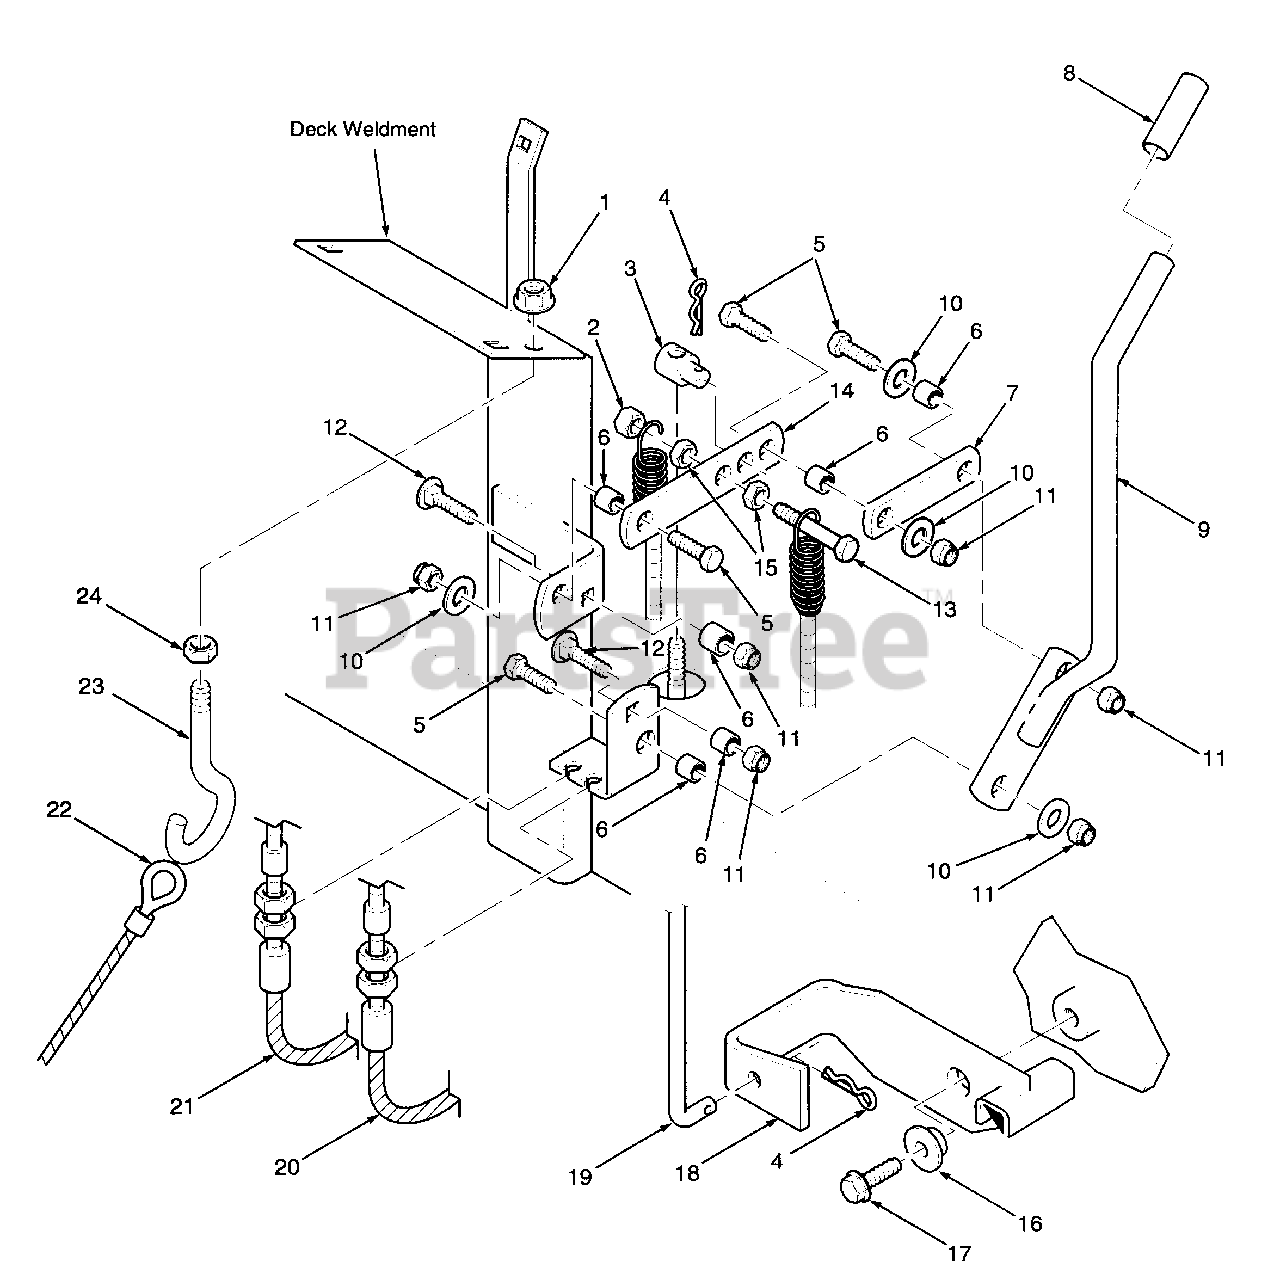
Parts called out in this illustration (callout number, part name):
1	Serr. Fl. HH Nut, 3/8-16
2	Hex Locknut, 3/8-16
3	Swivel
4	Hairpin Cotter (.094 x 1.62)
5	Hex Head Bolt, 3/8-16 x 1-1/4"
6	Sleeve, Hydro Linkage
7	Link, Cam
8	Grip, Parking Brake
9	Handle, Parking Brake
10	Flat Washer, 3/8 (.391 x .938 x .105)
11	Hex Nut, Elastic Stop 3/8-16
12	Carriage Bolt, 3/8-16 x 1-1/4"
13	Hex Head Bolt, 3/8-16 x 1-3/4"
14	Lever, Brake
15	Hex Jam Nut, 3/8-16
16	Washer, Neutral Lock
17	Serr. Fl. HH CPSCR, 3/8-16 x 1"
18	Bracket, Neutral Lock
19	Rod, Neutral Lock
20	Cable Assembly, Parking Brake R.H.
21	Cable Assembly, Parking Brake L.H.
22	Cable Winch
23	Eye Bolt, 3/8-16 R.H.
24	Hex Nut, 3/8-16
